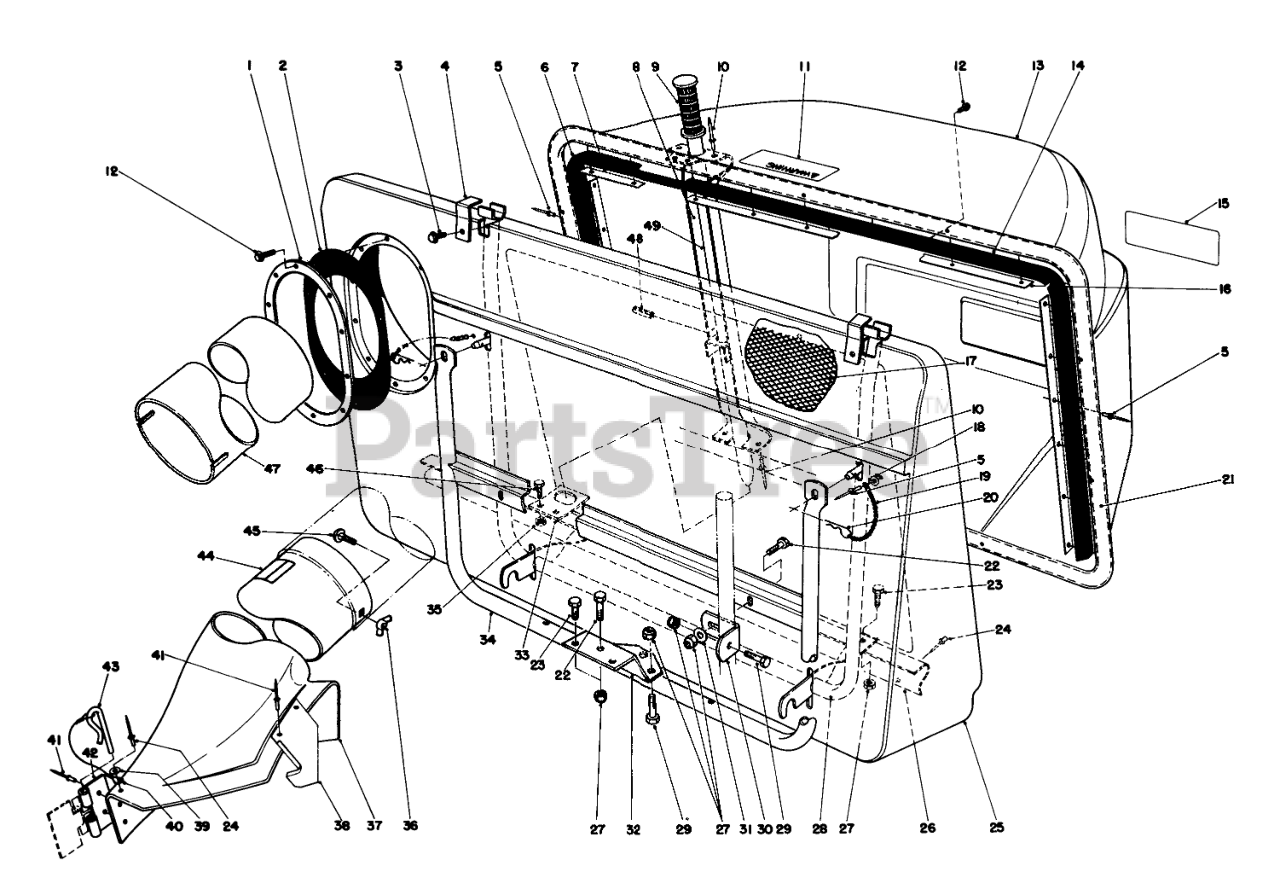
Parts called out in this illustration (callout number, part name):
1	RING-RETAINING
2	RING-RETAINER, RUBBER
3	SCREW-HWH
4	RETNR PIVOT BRKT
6	RH BAG SEAL
7	RETNR TOP EXT.
8	DUMP HDLE CHANL WA
11	Decal Warning
12	SCREW-HWHTF
13	REAR GRASS BASKET
14	Seal-Bag LH.
15	EASY EMPTY BAG DECAL
16	BAG RETNR EXT.
17	Screen Bag
18	WASHER
19	10 LINK CHAIN W/O HOOK
20	PIN-HAIR
21	BAG SUPT ASM FRM
22	SCREW-HH
23	SCREW-HH
24	RIVET-BLIND
25	Bag Front
26	FRAME SUPT BRKT B
27	NUT-LOCK, CONE
28	Bag Frame
29	SCREW-HH
30	Bracket Mtg. Grass Catcher
31	WASHER-PLAIN
32	MTG PLATE B
33	Hanger-Frame Lower
34	BAG SUPPORT WA
35	NUT-LOCK, CONE
36	NUT-WING SPECL
37	Chute Assembly (Incl. Ref. #24, 38-44)
38	CHUTE SUPT BRKT
39	WASHER-PLAIN
40	LANYARD
41	RIVET-BLIND
42	BRACKET-MOUNTING, CHUTE
43	PIN-LOCKING, CHUTE
44	DECAL-DANGER
45	BOLT-CARR
46	SCREW-HH
47	TUBE(ROUND&LONG)
48	PIN-ROLL
49	DUMP HANDLE ASM
